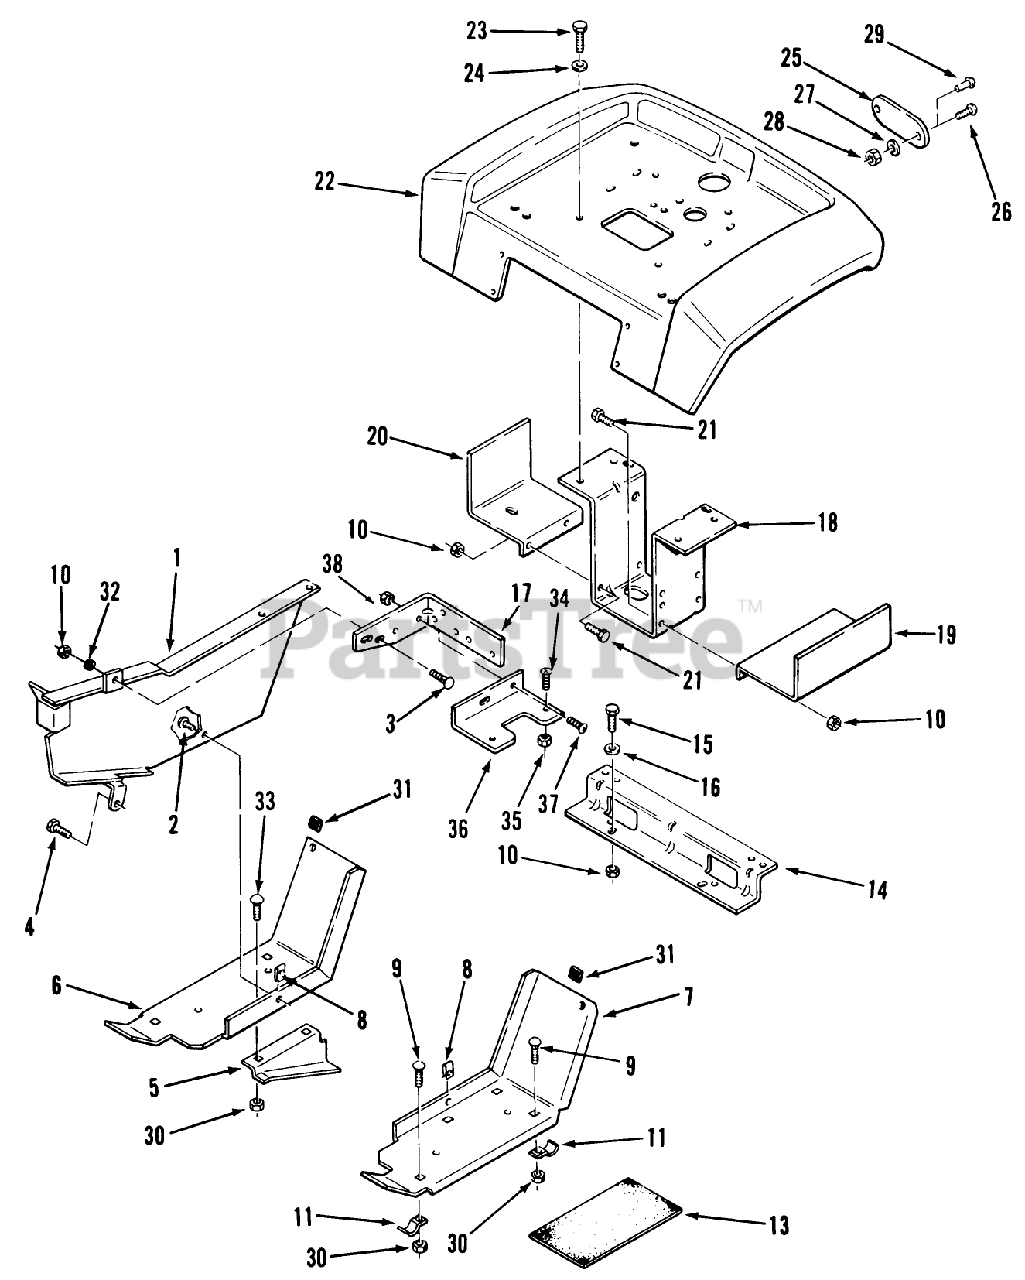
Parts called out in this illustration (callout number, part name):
3	BOLT-CARR
4	SCREW
7	FOOTREST LH *R
9	BOLT-CARR
11	BRACKET
13	PAD FOOTREST
16	WASHER 5/16 SAE
17	BRACKET-BELT*B
23	SCREW
24	WASHER 5/16 SAE
31	BUMPER
36	BRKT-FUS HLDER*B
